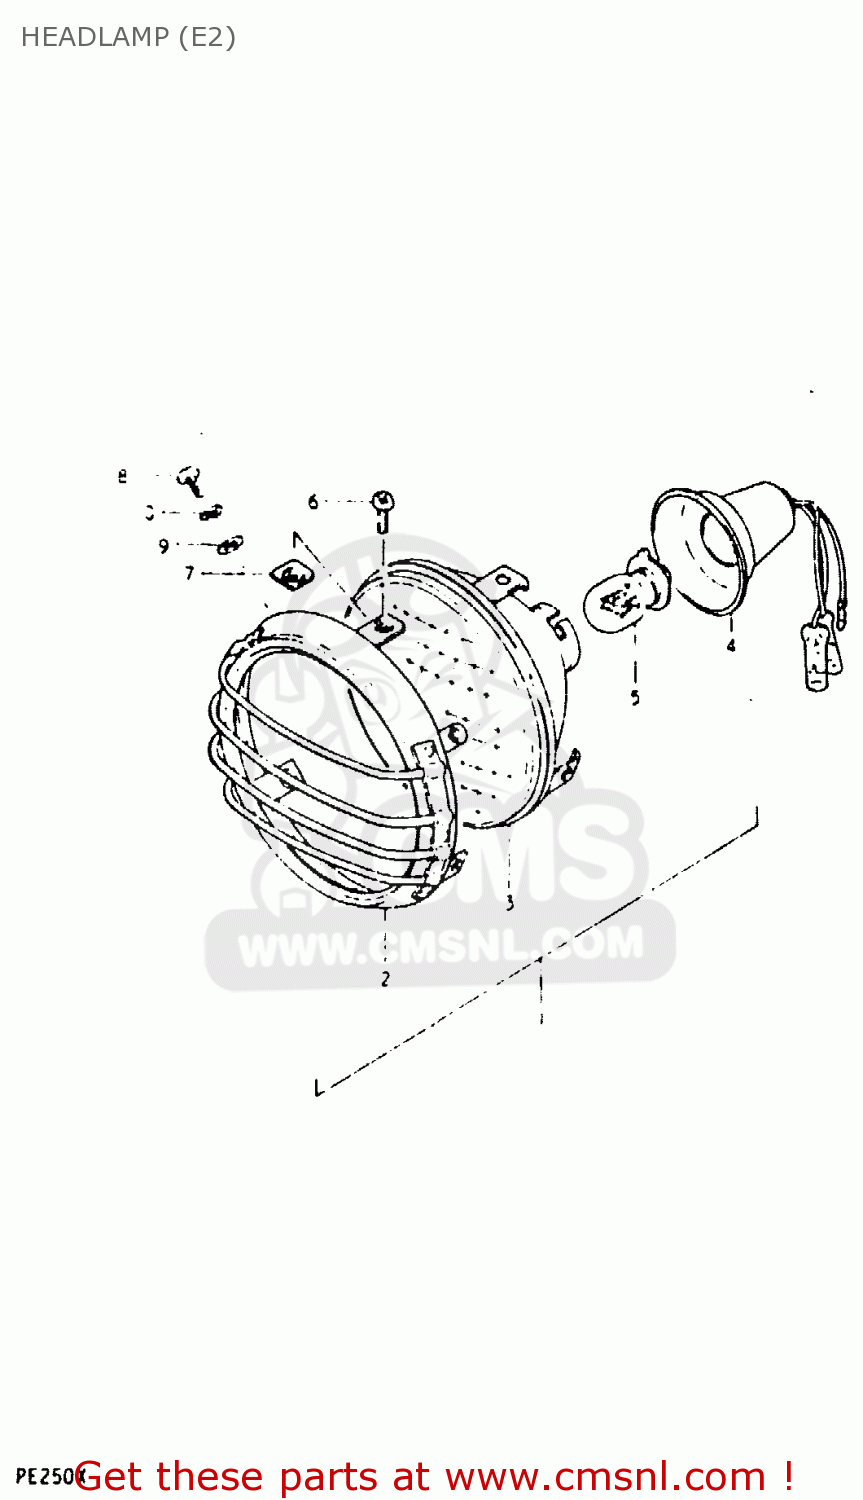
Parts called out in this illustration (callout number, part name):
1	HEADLAMP ASSY
2	RIM,HEADLAMP
3	LAMP UNIT
4	SOCKET,HEADLAMP
5	BULB (7V,18/18W)
6	SCREW
7	NUT
8	SCREW
9	WASHER
10	LOCK WASHER
